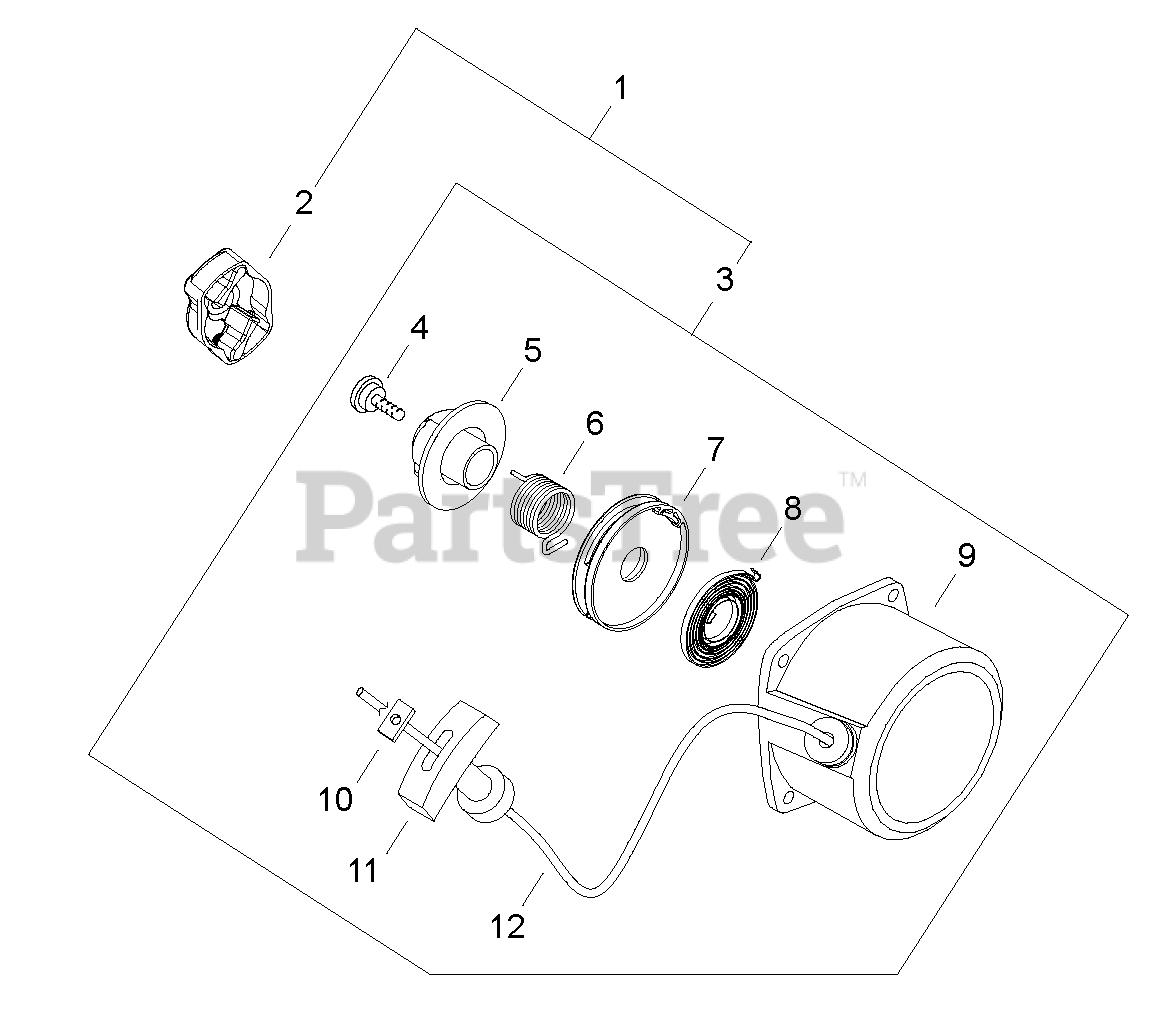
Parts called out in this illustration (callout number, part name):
1	EASY-TO-PULL RECOIL STARTER KIT
2	REEL, ROPE
3	STARTER ASSY
4	SCREW - 5
5	CAM
6	SPRING
7	REEL, ROPE
8	SPRING
9	CASE, STARTER
10	RETAINER, ROPE
11	GRIP, STARTER
12	ROPE, STARTER
